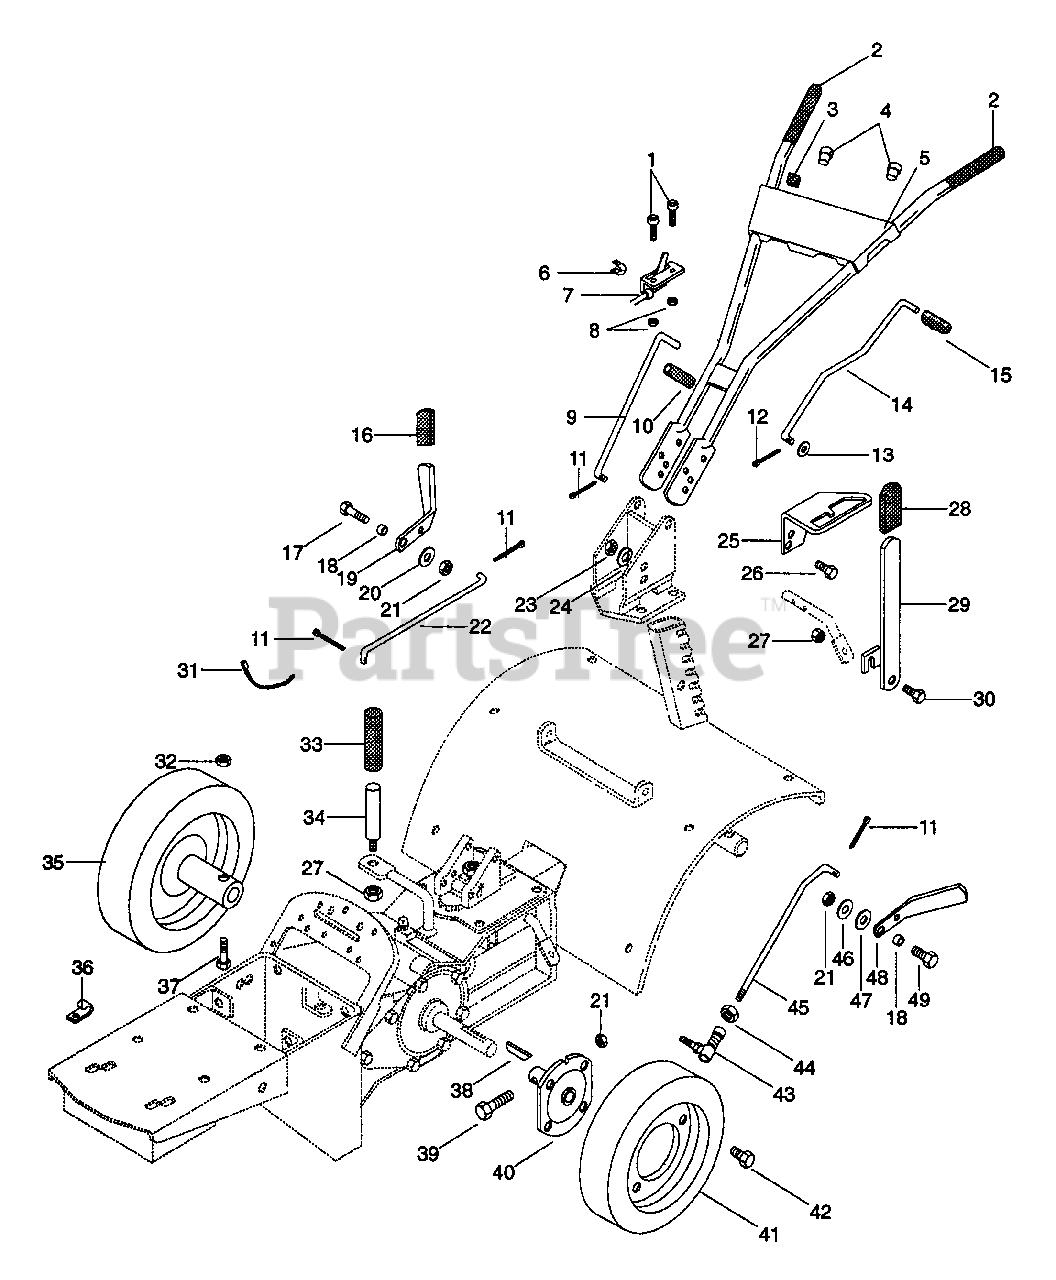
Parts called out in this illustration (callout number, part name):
1	SCR-MCH 10-24X.50 SLRH PL
1	SCR-MCH 10-24X.50 SLRH BL
2	HANDLEGRIP
3	KNOB, CONTROL-THROTTLE
4	SNAP BUSHING
5	HANDLE BAR
5	HANDLEBAR
6	CABLE RETAINER
7	THROTTLE CONTROL
8	NUT-KEPS 10-24 PL
9	POSITION ROD
10	GRIP - 5/16 ID X 2 7/8 - BLACK
11	PIN-COTR .09X.75 PL
12	PIN-COTR .12X1.0 PL
13	WSHR-FL-STL.344X.688X.065PL
14	CLUTCH ROD
15	GRIP - 3/8 ID X 2 7/8 - BLACK
16	GRIP
17	BLT-HEX .31-18X1.25 PL GR2
18	SPACER BUSHING .5 X .32 X .21
19	DRIVE CLUTCH HANDLE
20	WSHR-FL-STL .38X.875X.083 PL
21	NUT-LK .312-18 GR A PL
22	DRIVE CLUTCH ROD
23	NUT-HEX .375-16
24	WSHR-LK .375X.115 HVY PL
25	QUADRANT
26	BLT-HEX .38-16X1.00 PL
27	NUT-FLG. .312-18 PL
27	NUT-LK-CTR .312-24 PL
28	GRIP
29	ENGAGING ARM
30	BLT-HEX .31-18X.63 PL GR 2
31	TIE DOWN
32	NUT-LK .437-14 GR A PL
33	GRIP - 1/2 ID X 4 1/2 - BLACK
34	CLUTCH ARM
35	WHL
35	TIRE
35	WHL 13X5.00-6
36	CLIP
37	BLT-HEX .44-14X2.00 PL GR2
38	KEY-FTHR .25X1.875X.25 SAE
39	BLT-HEX .31-18X2.00 PL GR2
40	WHEEL HUB
41	T/WHL ASSY
41	T/WHL ASSY 4.80-8
41	TIRE
41	TIRE 4.80-8 NHS
41	WHL
42	SCR-TAP .500-20X.62 HH PL
43	SNAP IN BALL JOINT
44	NUT-HEX .312-24 PL
45	TILLER CLUTCH ROD
46	WSHR-FL-STL .344X1.375X.075 PL
47	SPACER .344X1.000X.375
48	TILLER CLUTCH HANDLE
49	BLT-HEX .31-18X.75 PL GR2
